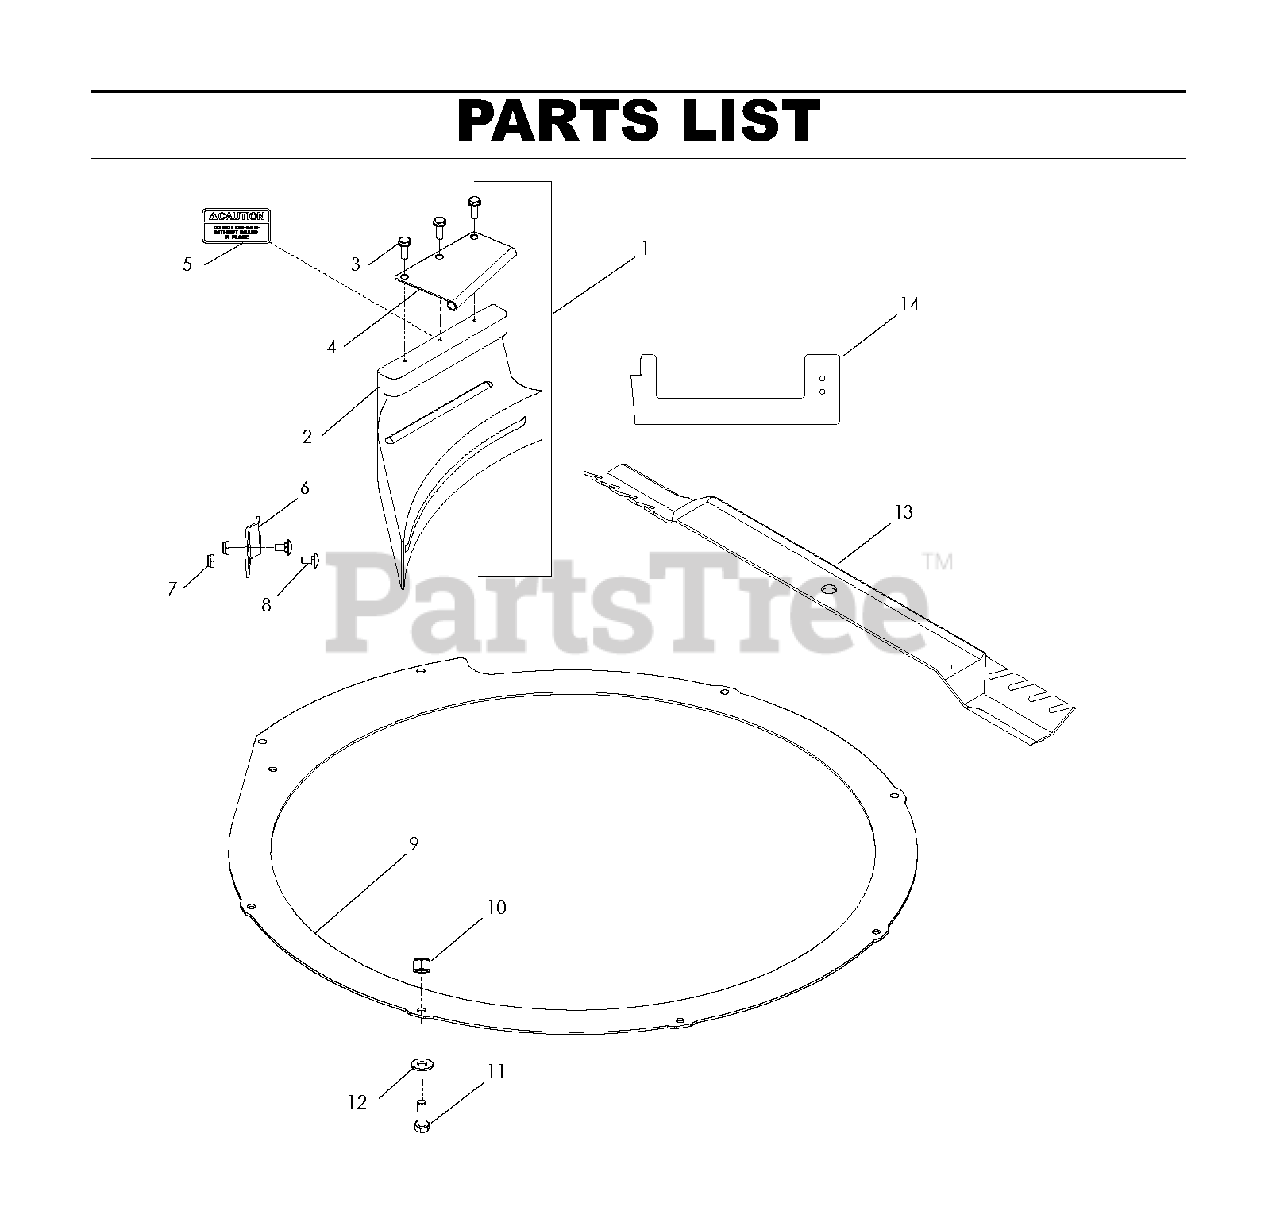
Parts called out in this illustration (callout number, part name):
1	PLUG, MULCHER ASSEMBLY
2	MULCHING PLUG R/B 2343
3	1/4-20 X 1/2 HWH FORM SCR H
4	BRACKET MULCHER
5	CAUTION DECAL-BLOWER
6	BOOT CLIP
7	JAM NUT 1/4C
8	RHSSNB 1/4-20 X 1/2
9	BOOSTER RING
10	NUT 1/4-20 NYLOC
11	HCS 1/4C X 3/4 HCS
12	WASHER 1/4 SAE
13	BLD 30" GATOR
